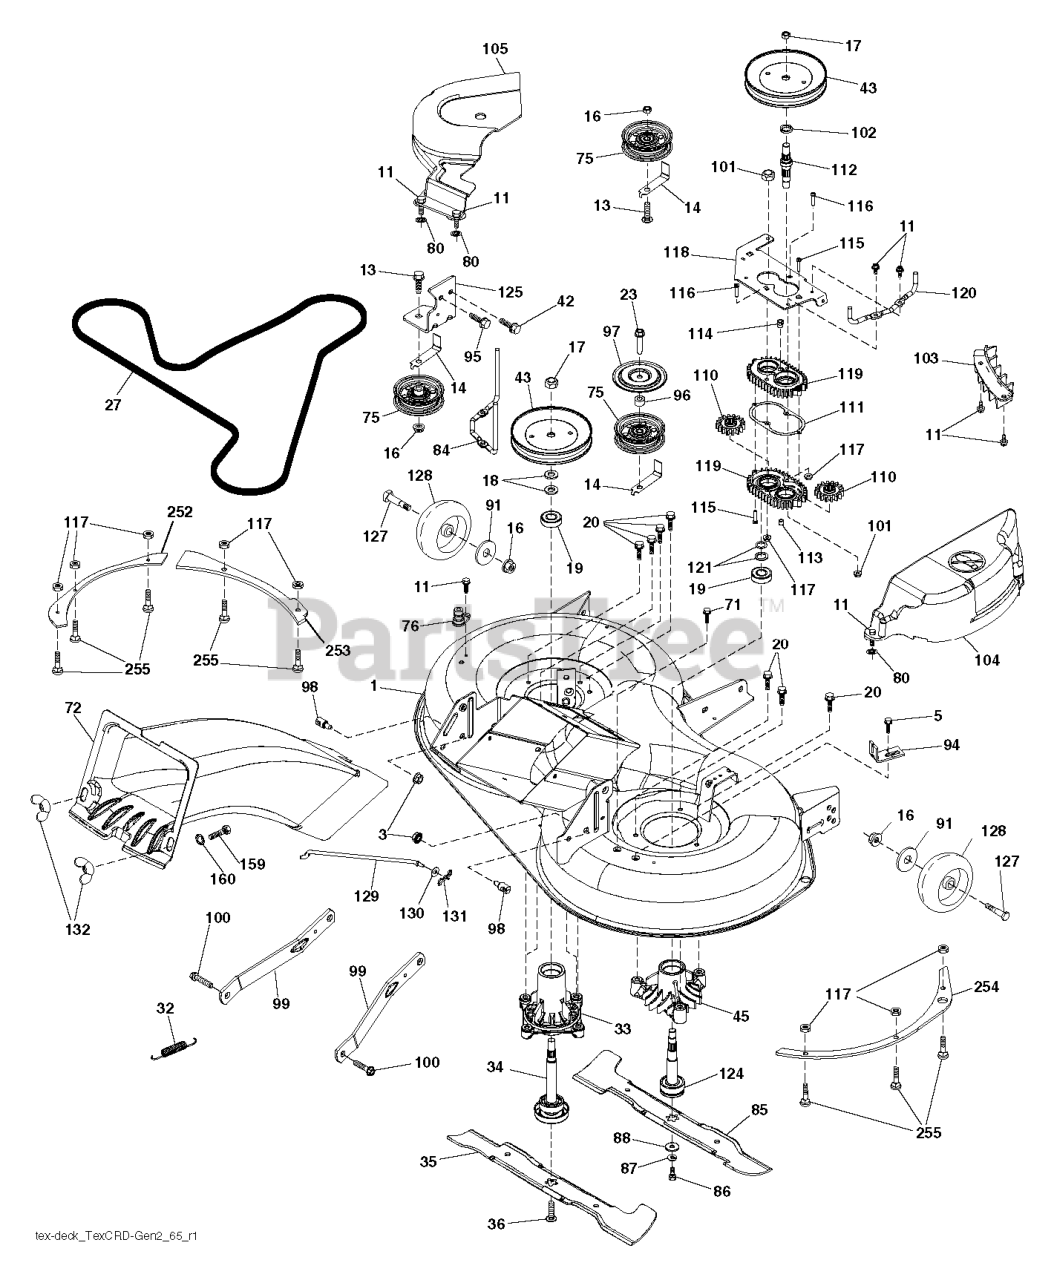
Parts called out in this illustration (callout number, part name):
1	DECK SVCX 97TXCRD 2GW 498
3	NUT LOCK HEX FLANGE 5/16-18
5	BOLT.5/16HEX.WHS.HD
11	SCREW.1/4-20X5/8
13	BOLT.3/8-16X1.50
14	KEEPER, BELT IDLER
16	NUT LOCK FLG 3/8-16 UNC
17	NUT.FLANGE.LOCK.TOP
18	WASHER.SPACER.MANDREL
20	SCREW, WASHER HEAD
23	SCREW LT
27	BELT 97CM ELECTRIC
32	SPRING 107CM & 97CM ELECTRIC D
33	RP.HOUSING.MANDREL.4PT.
34	SHAFT.ASM.MDRL.N/GREASE.38
35	BLADE.3N1.LH.CRD.97
36	BOLT.WASHER.ASM.7/16-2
42	SCREW
43	PULLEY.MANDREL.5.0.PD.38"
45	HOUSING.MANDREL.44/46" VENT
71	SCREW 3/8-16X1/2
72	CHUTE REAR CRD UPPER CHUTE TEX
75	FLAT IDLER PULLEY
76	PORT.WASHOUT
80	PALNUT 1/4
84	BELT KEEPER.MANDREL.38"COATED
85	BLADE.3N1.RH.CRD.97
86	BOLT.3/8-24X1.25GR8. LHTHRD
87	LOCKWASHER
88	WASHER.BLADE
91	WASHER
94	BRKT.CLUTCH.CABLE
95	SCREW, 3/8-16X3/4
96	SPACER
97	PROTECTOR
98	STUD.FASTNER.W/ANTI-ROTATE
99	ARM.SUSPENSION.MOWER.R
100	BOLT.SHOULDER
101	NUT.CROWNLOCK.9/16 -18.UNC
102	SPACER BEARING
103	GUARD GUARD FRONT VENT
104	97.CRD.RH.MANDREL.COVER
105	MANDREL MANDREL COVER LH
110	CRD.SPUR.GEAR
111	GASKET GASKET GEARCASE
112	SHAFT SHAFT. CRD GEARCASE ADAP
113	PLUG PLUG OIL
114	VALVE VALVE RELIEF
115	SCREW
116	BOLT.CARIGE.SS.1/4-20X1.75GR5
117	NUT T
118	ARM ARM CLUTCHING
119	GEARCASE GEARCASE SUBASM
120	BRACKET KEEPER BELT RH
121	WASHER WASHER
124	MANDREL SHAFT NON/GREASE
125	BRACKET BRACKET IDLER CHASSES
127	BOLT.SHOULDER.3/8-16X3-5/8.
128	RP WHEEL. GUAGE RALLY
129	ROD.ANTI.SWAY.48/54"K4
130	WASHER
131	PIN.COTTER.5/16.BOW TI
132	KNOB.HANDLE.3/8.TRI-POINT.BLAC
159	BOLT
252	PLATE 97 LEFT BOLT REINFORCING
253	PLATE 97 LH SIDE BOLT ON
254	PLATE 97 RH SIDE BOLT ON
255	RHSNB, 1/4-20 X 1, GR5
